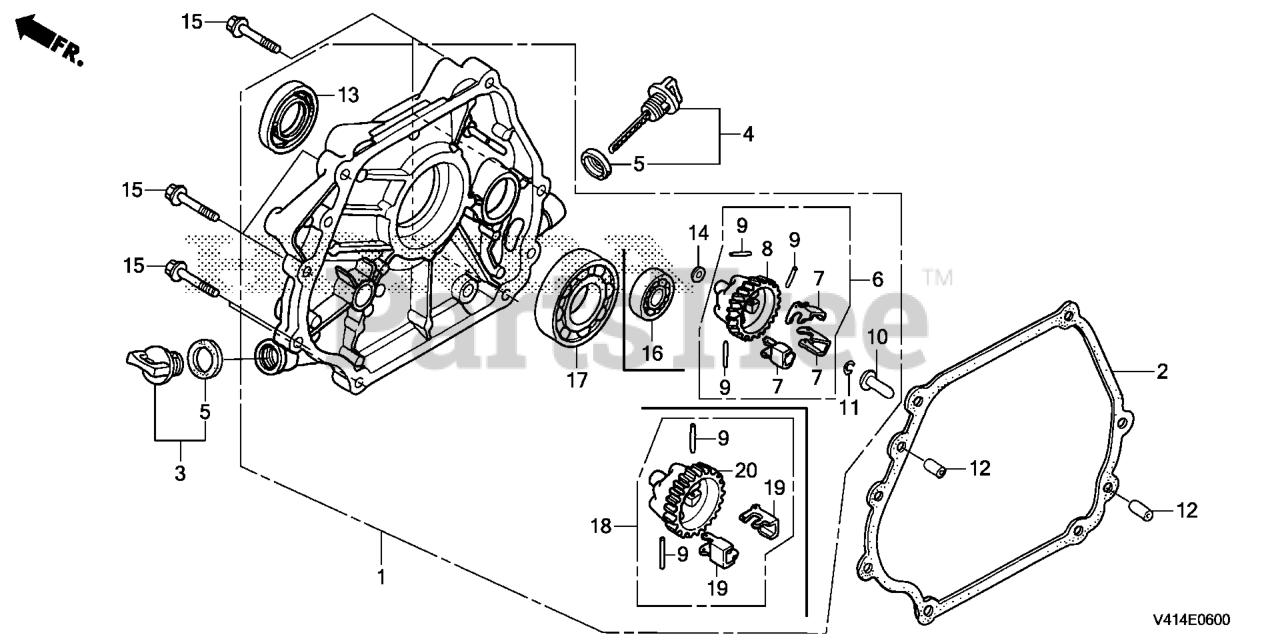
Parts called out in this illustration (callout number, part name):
1	COVER ASSY., CRANKCASE
2	GASKET, CRANKCASE COVER
3	CAP ASSY., OIL FILLER
4	CAP ASSY., OIL FILLER
5	GASKET, OIL FILLER CAP
6	GOVERNOR ASSY.
7	WEIGHT, GOVERNOR
8	HOLDER, GOVERNOR WEIGHT
9	PIN, GOVERNOR WEIGHT
10	SLIDER, GOVERNOR
11	CLIP, GOVERNOR HOLDER
12	PIN, DOWEL (8X12)
13	OIL SEAL (35X52X8) (NOK)
14	WASHER, PLAIN (6MM)
15	BOLT, FLANGE (8X40) Use up to Engine SN 1003236.
16	BEARING, RADIAL BALL (6202)
16	BEARING, RADIAL BALL (6202) (FUJIKOSHI)
17	BEARING, RADIAL BALL (6207)
